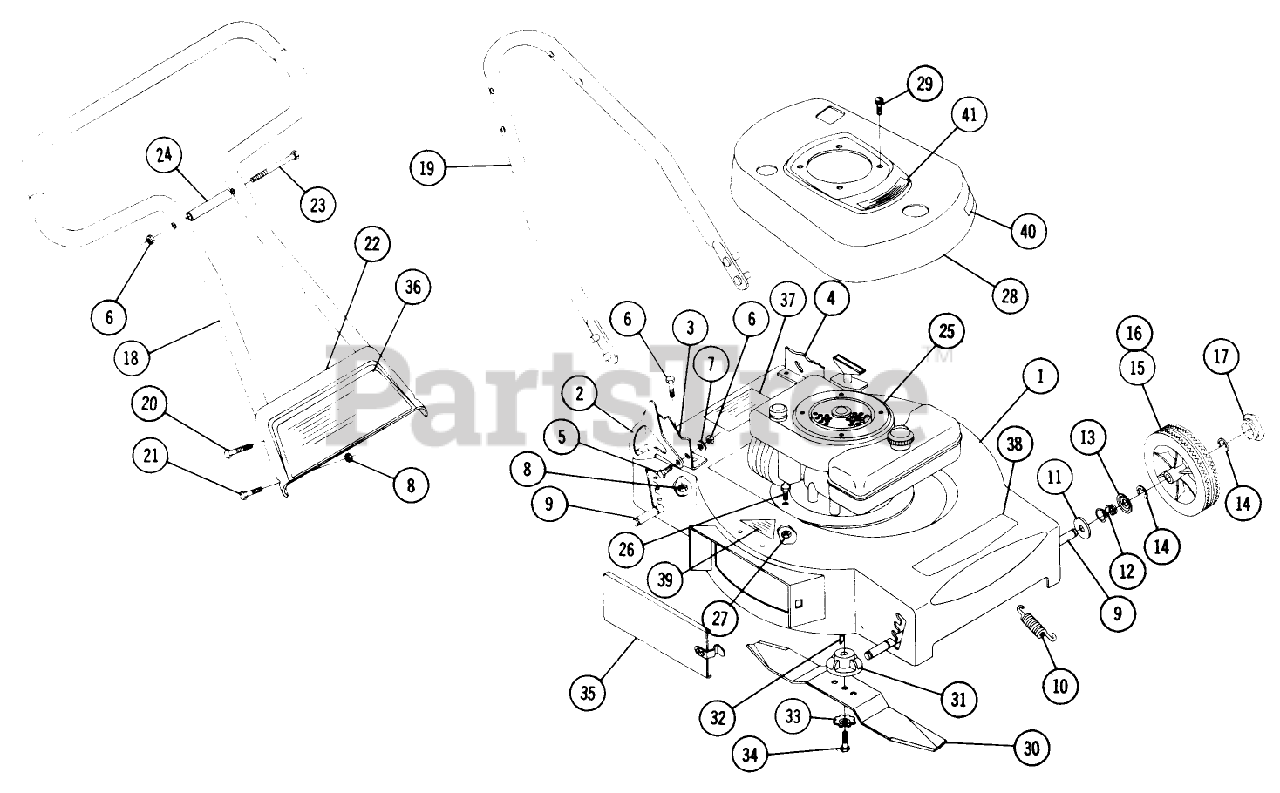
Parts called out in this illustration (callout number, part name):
1	Ass-y. Deck
2	Latch-Handle Mounting
3	Bracket Handle R.H.
4	Bracket Handle L.H.
5	Bolt-1/4-20 x 5/8
6	Nut-Nylok
7	Washer
8	Nut Hex 5/4-20 Nylok
9	Shaft-Axle
10	Spring-Idler
11	Washer
12	Spring-Wheel
13	Washer-Cup
14	Lock Rod
15	Wheel-Rear 8"
16	Wheel-Front 7"
17	Hubcap
18	Handle, Upper
19	Ass-y. Handle-Lower
20	Bolt 1/4-20 x 1 1/2
21	Bolt 1/4 20 x 1 1/4
22	Shield-Handle
23	Bolt Hex 1/4-20 x 4 1/2
25	Engine-2 Cycle
26	Bolt Hex 5/16-18
27	Nut-Nylok
28	Shroud-Engine
29	Screw Sems 1/4-28 x 3/8
30	Blade 18" Rotary
31	Drive Blade
32	WOODRUFF KEY
34	Bolt 3/8-24 x 1 1/4 Nylok
35	Ass-y. Plate-Mulching
37	4XC6485 GIS ROTARY
38	Decal-Reo Logo
39	Decal-Caution
40	Decal-Shroud-Throttle
41	Decal
